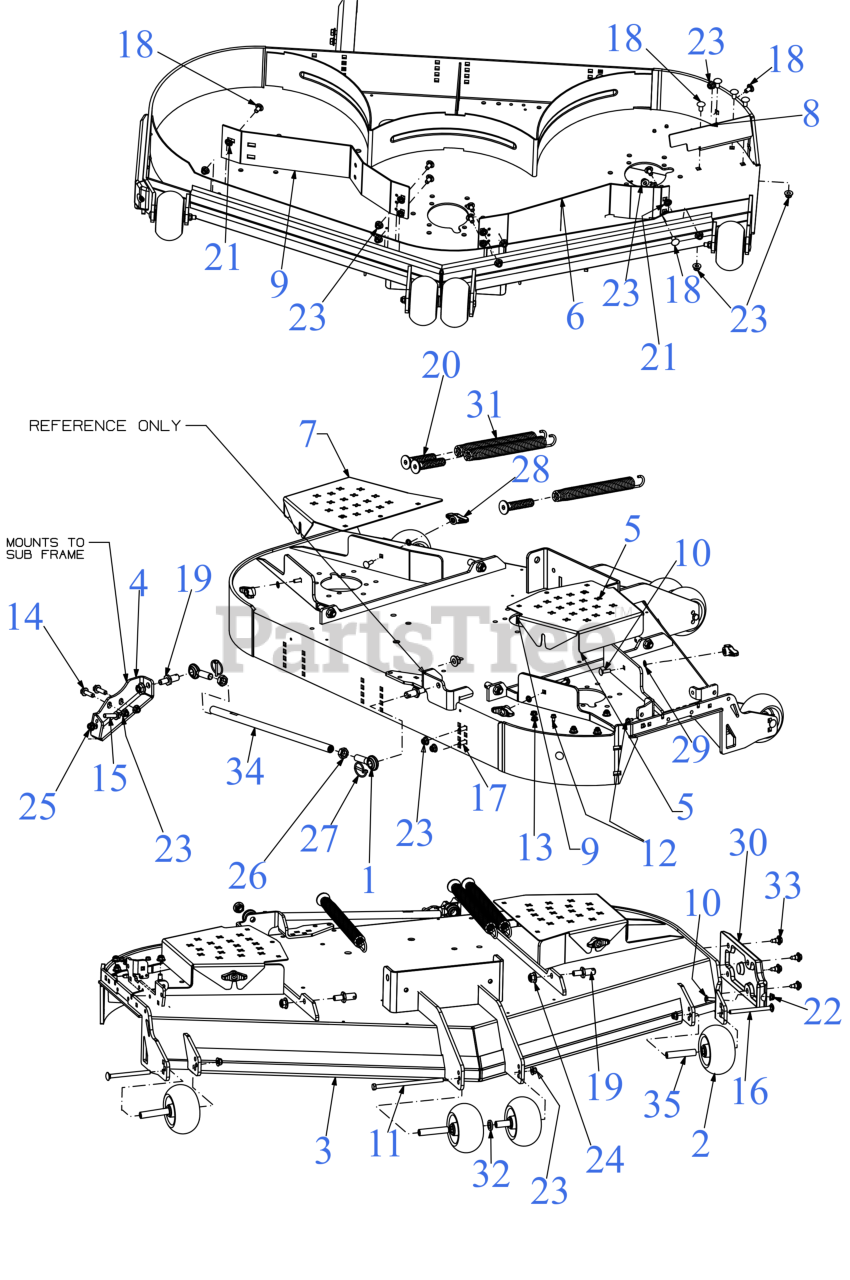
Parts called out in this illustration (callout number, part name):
1	MALE ROD END
2	5" DIA DECK WHEEL COMPLETE
2	WHEEL BUSHING
3	60" FAB DECK SHELL
4	STABILIZER MOUNTING BRACKET
5	DECK BELT COVER
6	DECK BAFFLE
7	BELT COVER
9	DECK BAFFLE
10	CARRIAGE BOLT 5/16-18 x 1.00
11	SCREW 3/8-16 x 7.25 GR5
12	SCREW 1/4-20 X.500
13	SCREW 5/16-18 x .500
14	SCREW 3/8-16 x 1.25 GR5
15	HEX HEAD BOLT (3/8-16:1.50 GR8)
16	CARRIAGE BOLT 3/8-16 x 4.25 GR5
17	CARRIAGE BOLT 3/8-16 x 1.00 GR5
18	CARRIAGE BOLT 3/8-16 x .75
20	SPRING INSERT SCREW
22	FLANGE LOCK NUT 5/16-18
25	LOCK NUT (3/8-16)
26	HEX JAM NUT 5/8-18
27	LYNCH PIN .1875
28	WING KNOB 5/16-18
30	DECK SKID PLATE (LH)
31	EXTENTION SPRING 1.20 x 11.35
32	FLAT WASHER .632X1.00X.16
33	SHOULDER SCREW .43X.29X5/16-18 TT
34	TUBE .565 X .750 X 18.75"LG
35	WHEEL SPACER .38ID x 3.04LG
